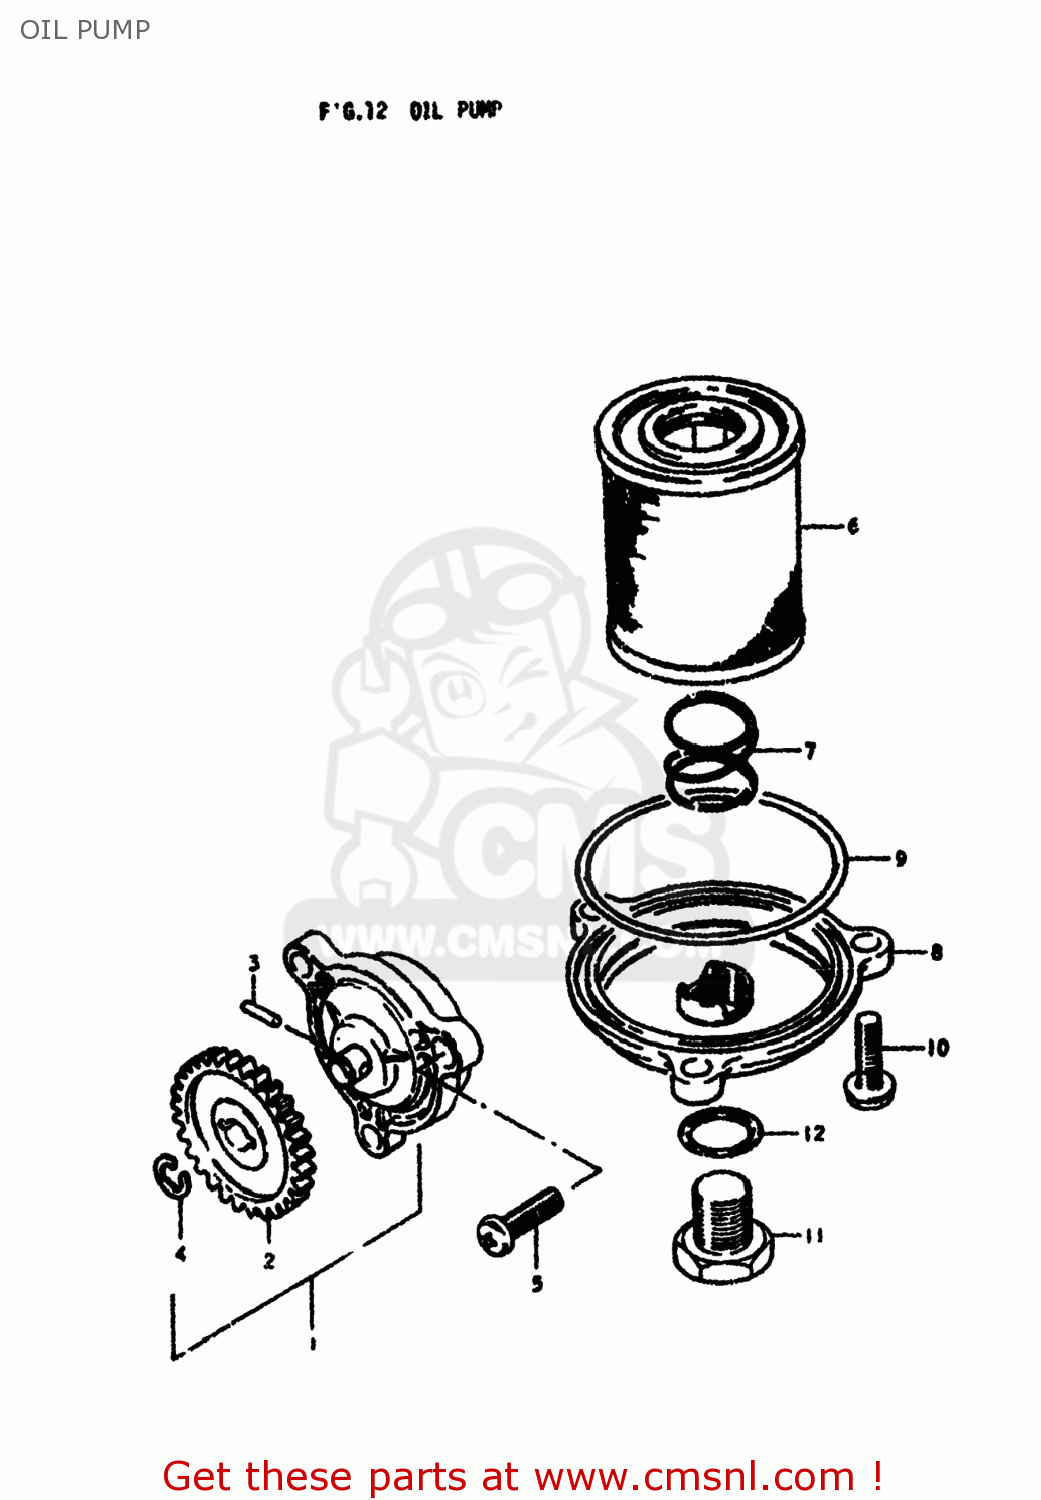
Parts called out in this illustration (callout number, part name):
1	PUMP ASSEMBLY,ENGINE OIL
2	GEAR,OIL PUMP DRIVEN
3	PIN(2.5X11.8)
4	E RING 6MM
5	SCREW
6	STRAINER,OIL
7	SPRING
8	CAP,ENGINE OIL STRAINER
9	O RING(D:2.4,ID:62.6)
10	BOLT,REAR
11	PLUG
12	GASKET(14X19.2X2) (NAS)
